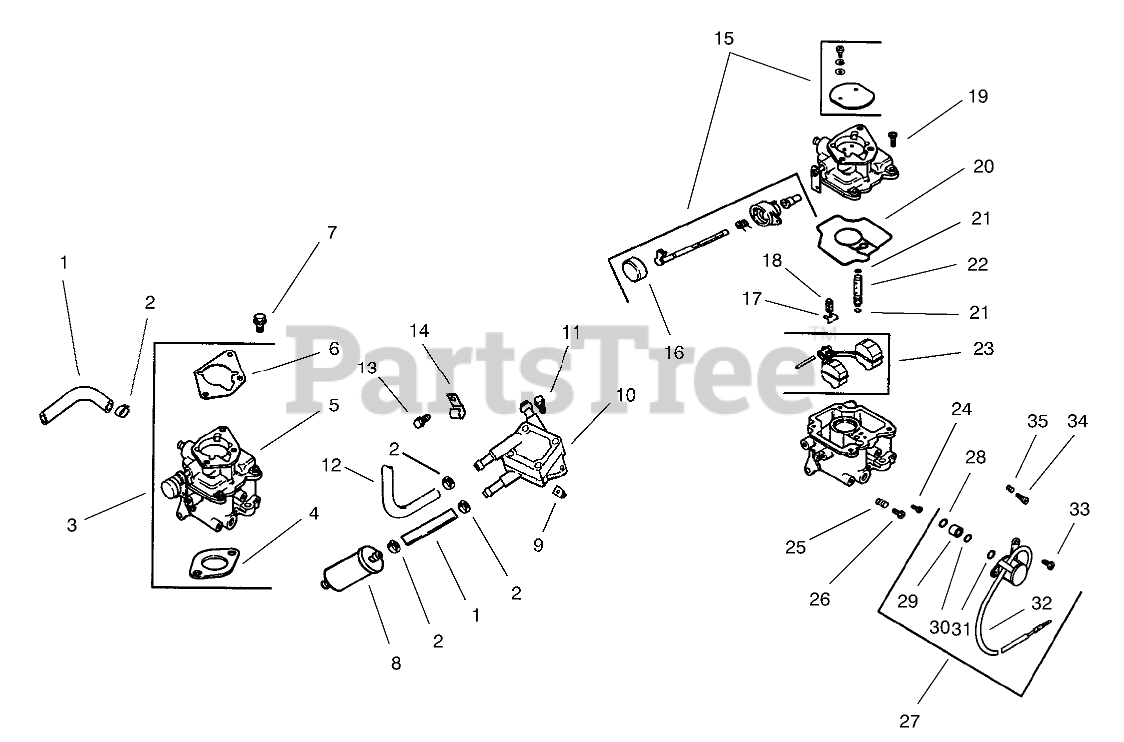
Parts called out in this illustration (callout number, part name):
1	Line fuel
2	Clamp
3	Kit, carburetor w/gasket (Includes 4-6)
4	Gasket
5	Carburetor assembly (Includes 15-35)
6	Gasket
7	Screw
8	Filter-Fuel
9	Nut
10	Pump-Fuel
11	Screw
12	Line, fuel17"
13	Screw
14	Clamp
15	Kit, choke repair (Includes 16)
16	Cap-Choke Lever
17	Clip, cable
18	Valve-Inlet Needle
19	Screw
20	Gasket-Body,Carburetor
21	"O"Ring
22	Jet-Slow
23	Roat Repair Kit
24	Jet-Main
25	Spring-Idle Speed Adj.
26	Screw, idle adjusting
27	Kit, solenoid (Includes 28-33)
28	O-Ring
29	Seat-Solenoid
30	O-Ring
31	O-Ring
32	Solenoid
33	Screw
34	Needle, idle
35	Spring-Idle Adj.
